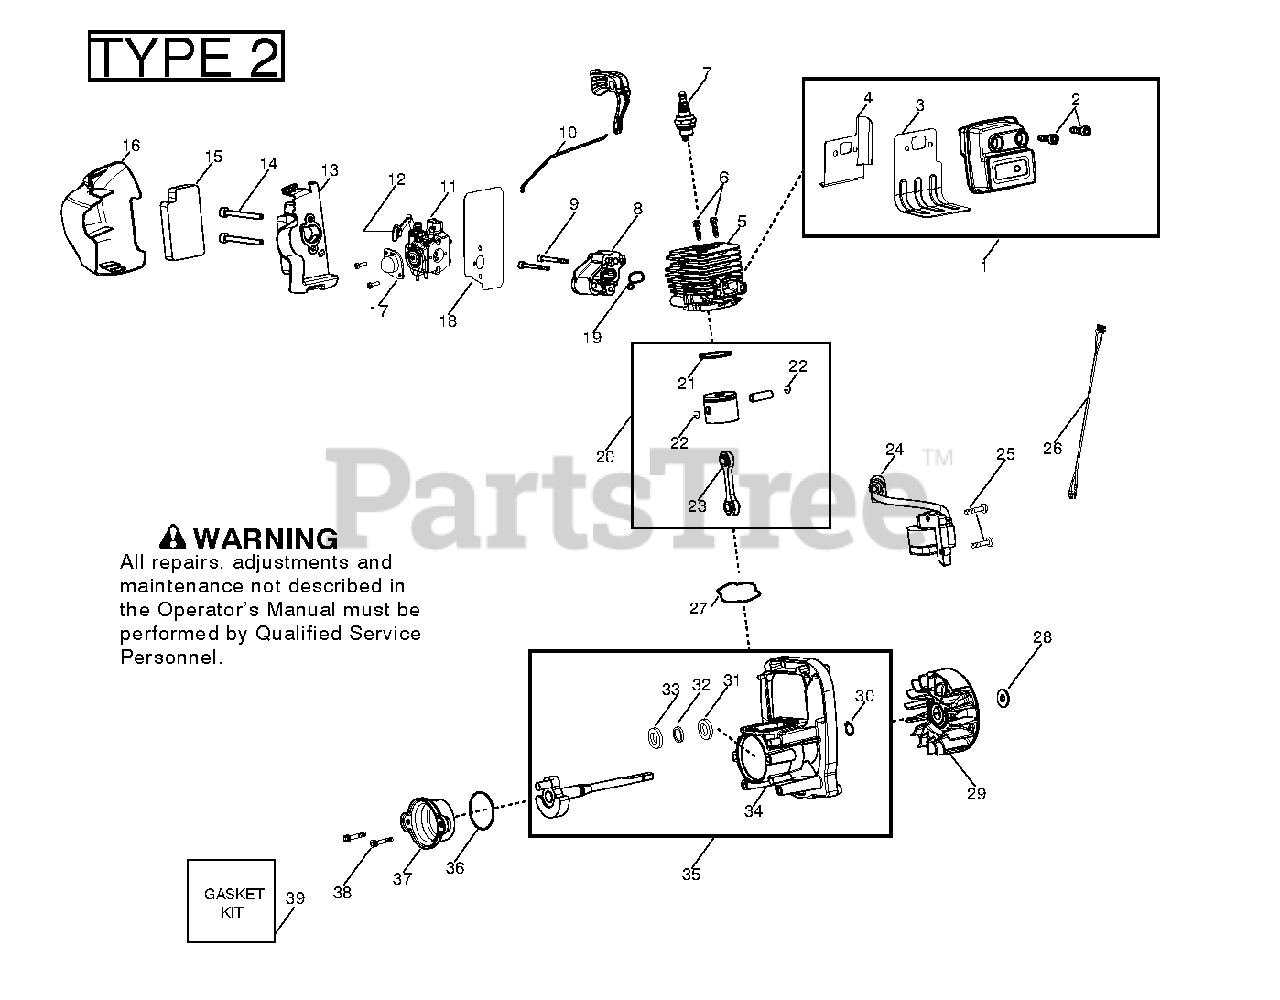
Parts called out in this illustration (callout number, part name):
1	ASSY MUFFLER WELDED
2	BOLT MUFFLER
3	KIT GASKET 25CC
4	SHIELD MUFFLER HEAT
5	CYLINDER CHROME 25CC
7	PLUG-SPARK (RCJ-6Y)
8	ADAPTER CARBURETOR
10	LINKAGE THROTTLE
11	KIT CARBURETOR WT-875A
12	CHOKE LEVER
12	LEVER CHOKE WT-875
13	BASE AIRBOX RED
15	AIR FILTER FOAM
16	COVER AIRBOX BLACK
17	PURGE BULB 188-16
18	KIT GASKET 25CC
19	KIT GASKET 25CC
20	KIT PISTON CONN ROD
21	RING-PISTON
22	WRIST PIN RET.
23	KIT PISTON CONN ROD FORGED
24	KIT MODULE W/0 INTERRUPT
26	HARNESS WIRE
27	KIT GASKET 25CC
28	WASHER FLAT
29	ASSY FLYWHEEL
30	RETAINING RING
31	OUTER BEARING
33	BEARING
34	ASSY CRANKCASE
35	ASSY CRANKCASE & CRANKSHAFT
36	KIT GASKET 25CC
37	ASSY REAR PLUG
39	KIT GASKET 25CC
